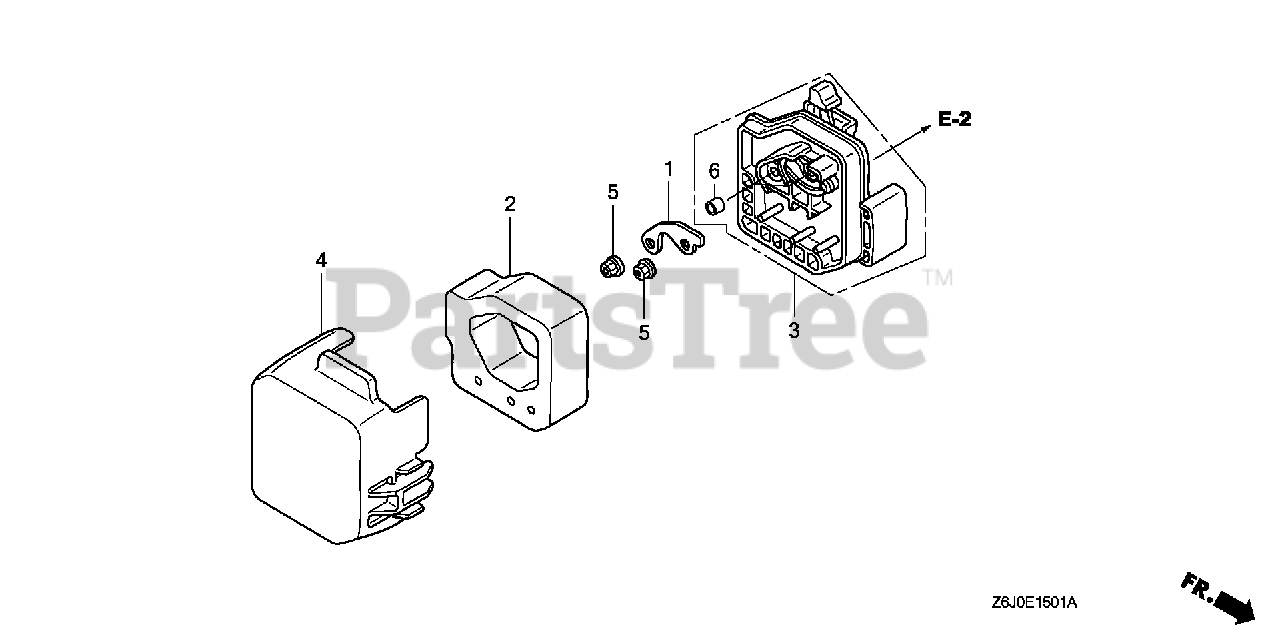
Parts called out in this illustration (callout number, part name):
1	PLATE, OIL TRAP
2	ELEMENT, AIR CLEANER
3	HOUSING, AIR CLEANER
4	COVER, AIR CLEANER
5	NUT, FLANGE (5MM)
6	COLLAR, AIR CLEANER
